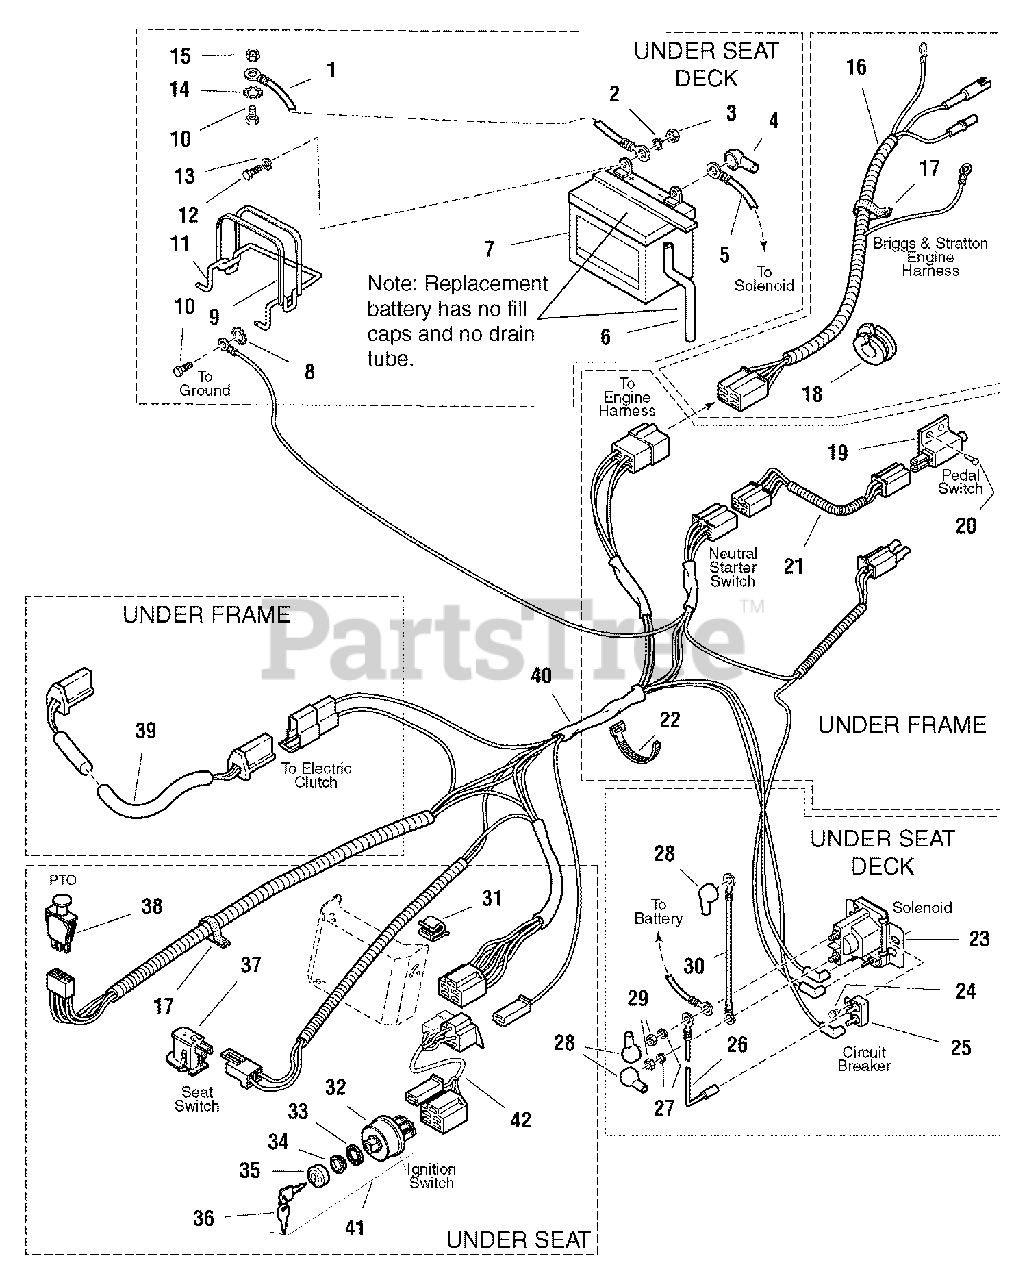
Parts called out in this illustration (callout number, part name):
1	CABLE, Battery to Ground
2	WASHER, Lock, 1/4
3	NUT, Hex 1/4-20
4	BOOT, Insulator
5	CABLE, Battery to Solenoid (Kohler Models)
5	CABLE, Battery to Solenoid (Briggs & Stratton Models)
6	TUBE, Vent (Early Models Only)
8	WASHER, Lock, External Tooth, 5/16
9	STRAP, Battery
10	CAPSCREW, Metric, M08-1.25 x 20 mm
11	BRACE, Battery
12	CAPSCREW, Hex Head, 1/4-20 x 3/4
13	WASHER
14	WASHER, Lock, External Tooth, 3/8
15	NUT, Hex, 3/8-16
16	WIRE ASSEMBLY, Harness to Engine (Briggs & Stratton Only)
17	CLAMP, Wire (11 HP B&S 5-Speed Only)
18	GROMMET (11 HP 5-Speed Models Only)
19	SWITCH, Neutral Start
21	WIRE ASSEMBLY, Neutral Switch (11 HP Coronet Only)
22	TIE, Self-Locking
23	SOLENOID
24	CAPSCREW, Hex Head, Taptite, 1/4-20 x 1/2
25	CIRCUIT BREAKER
26	WIRE ASSEMBLY
27	LOCKWASHER, 5/16
28	COVER, Terminal
29	NUT, Hex, 5/16-24
30	CABLE, Solenoid to Starter
31	CLIP (14 HP Hydro Qty=1)
32	SWITCH, Ignition (6 pole)
33	WASHER, Internal Tooth, 5/8
34	NUT
35	COVER, Keyswitch
36	KEYS (Set of 2 Keys)
37	SWITCH, Seat, Gray Switch, Gray Retainer
37	SWITCH, Seat, Gray Switch, Black Retainer
38	* SWITCH, PTO, Electric Clutch
39	WIRE ASSEMBLY, Clutch
40	HARNESS, Wiring
41	IGNITION KEY SWITCH ASSEMBLY
42	HARNESS, Wiring Extension
